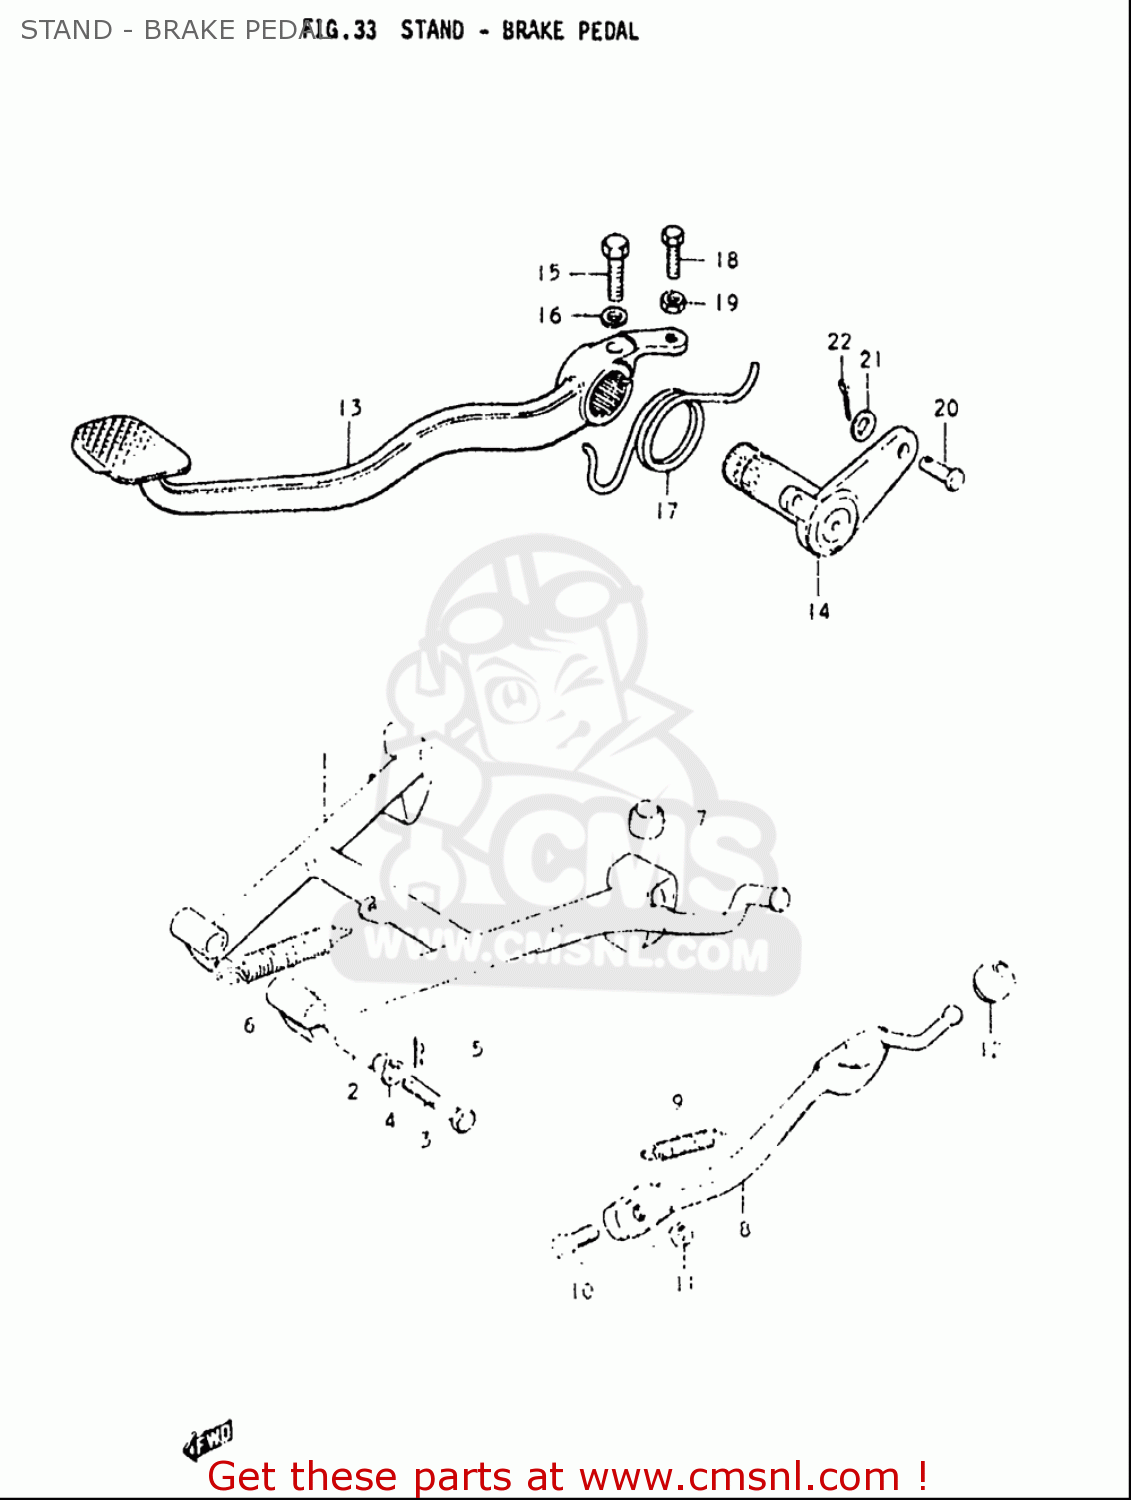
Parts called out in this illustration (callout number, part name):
2	SPACER(10X16X38.8)
3	BOLT(10X65)
4	WASHER,LOCK
5	CLIP
6	SPRING
7	CUSHION
9	SPRING
10	BOLT(10X30)
11	NUT
12	CUSHION
15	BOLT
16	WASHER,LOCK
17	SPRING
18	BOLT
19	NUT
20	PIN
21	WASHER
22	PIN
